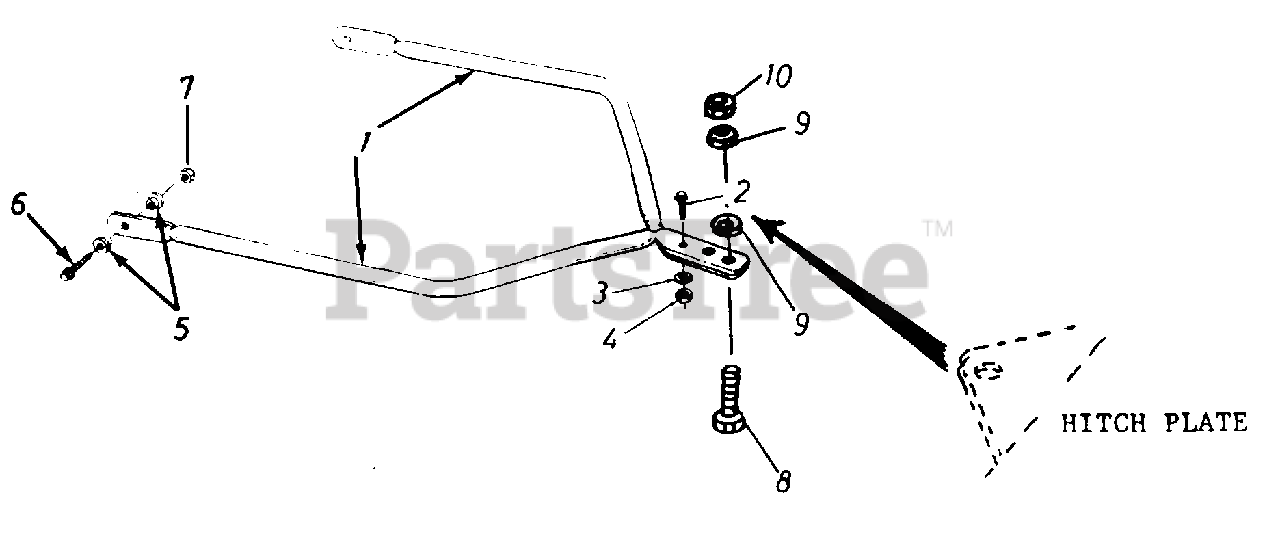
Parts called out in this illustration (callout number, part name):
3	L.-Wash. 1/4" I.D
4	Hex Nut 1/4-20 Thd.
5	Shoulder Spacer
6	Hex Wash. Hd. Self-Tapp Scr. 5/16-18 x 1.0" Lg.
7	Hex Nut 5/16-18 Thd.
8	Shld. Bolt .496 Dia. :
9	Belle-Wash. .39 I.D. x 1.12 O.D.
10	Hex Jam L-Nut 3/8-16 Thd.
